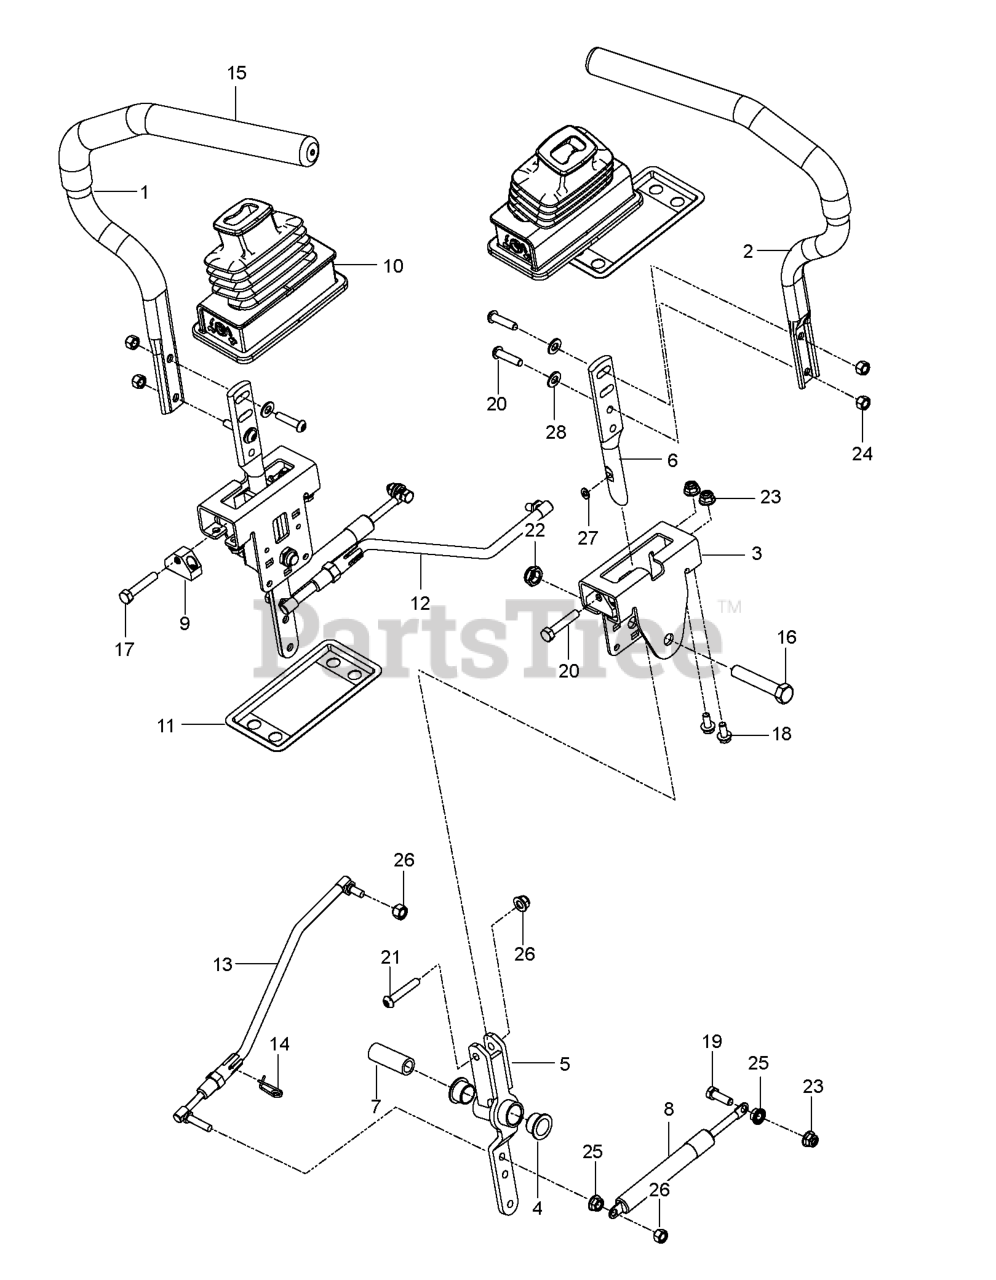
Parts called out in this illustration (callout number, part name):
1	TUBE.LEVER.CNTL.ASM.ZTR.RT.SVC
2	TUBE.LEVER.CNTL.ASM.ZTR.LT.SVC
3	BRACKET.CONTROLS.ZTR.X431
4	BEARING, FLANGE
5	LEVER CONTROL PIVOT
6	CONTROL.LEVER.HANDLE
7	SPACER.PIVOT.CONTROL
9	BLOCK TRACKING CONTROL ZTR
10	BOOT.STEERING.LEVER
11	CONTROL.BOOT.FLANGE.X431
12	ROD.ASM.RH.ADJUSTABLE
13	ROD.ASM.LH.ADJUSTABLE
14	RETAINER.CLIP.SPRING.S
15	PURCHASE THE COMPLETE LEVER
16	HCS 1/2-13 X 2-3/4 GD 5 ZD
17	SCREW.SHAKEPROOF.1.25.BLACK
18	HHFS 5/16-18 X 3/4
19	BOLT.FIN.HEX.5/16-18UNC X 1.00
20	BUTTONHEAD.5/16-18X1.125.BLACK
21	SCREW 5/16-18 X 1 3/4 BTN-HD
22	NUT 1/2-13 HEX JM NYL
23	5/16-18 NYLOC FLANGE NUT
24	NYLOCK.NUT.5/16-18 BLACK
25	NUT 5/16C WHIZ
26	NUT.71038.31-18.HEX.NYLOCK
27	WASHER.11/32ID.11/16OD.116THIC
28	WASHER.11/32X11/16 BLACK
